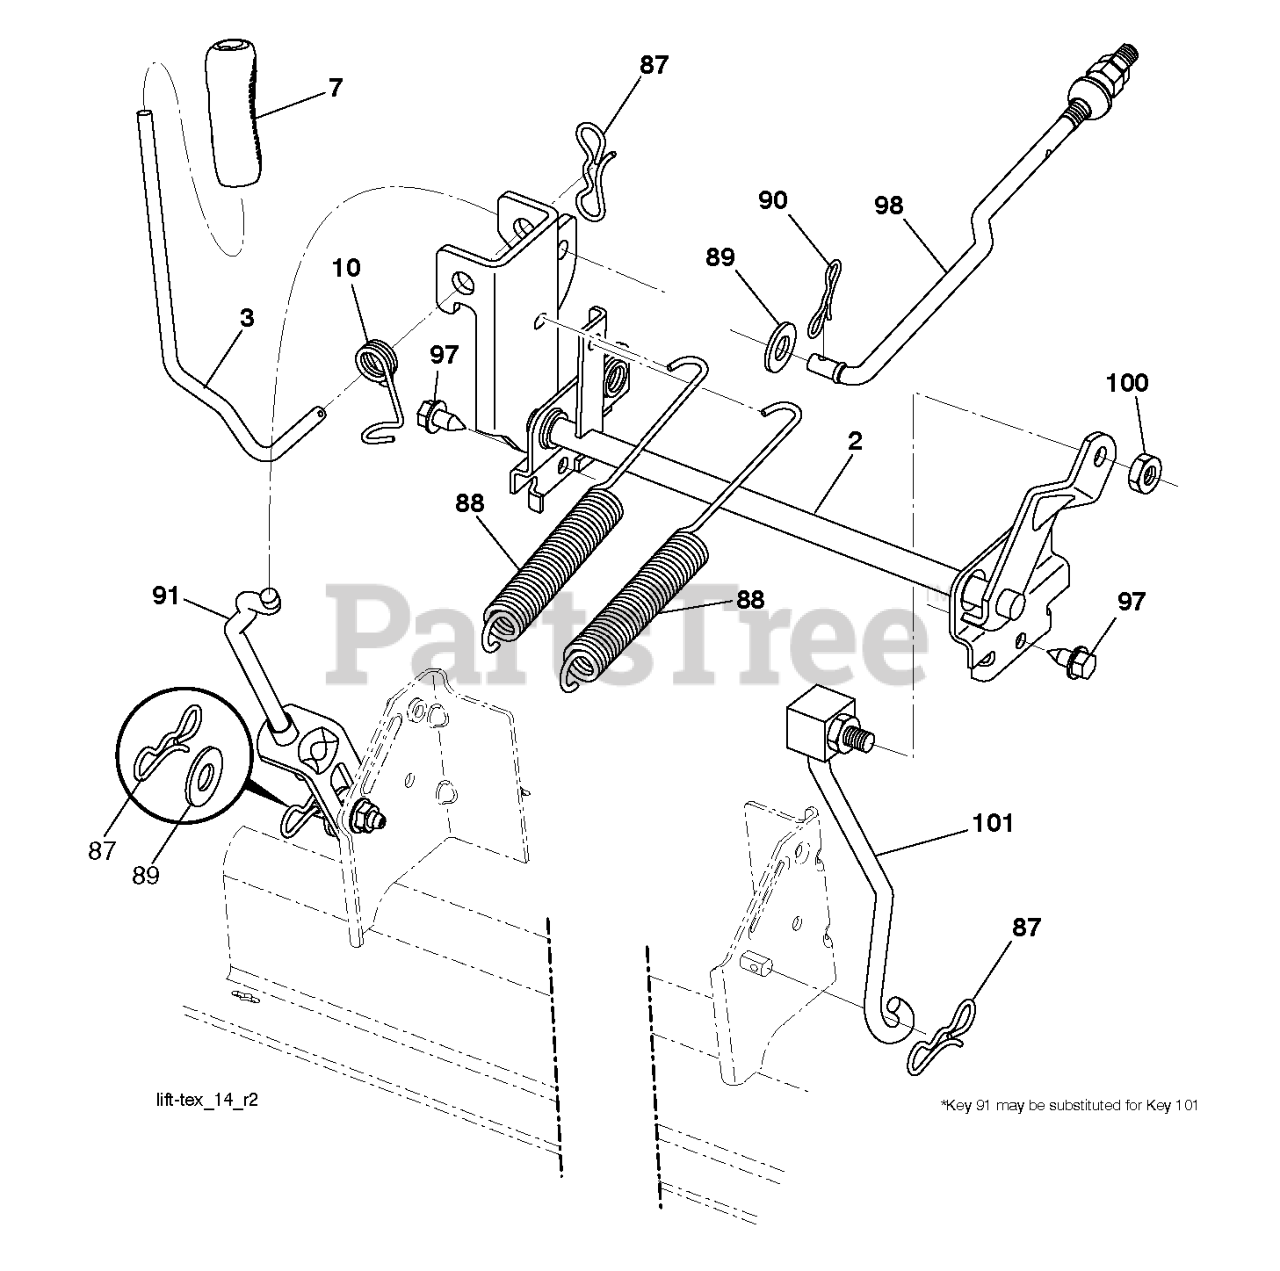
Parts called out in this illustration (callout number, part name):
2	SHAFT.ASM.LIFT.CROSS.H
3	LEVER.LIFT.HANDLE.LT
7	GRIP.HANDLE.LIFT.PVC.BLACK
10	SPRING.TORSION.LIFT.HANDLE
87	PIN.COTTER.7/16.BOW TI.
88	SPRING.LIFT.ASSIST
89	WASHER.CLEAR.ZINC
90	PIN.COTTER.5/16.BOW TI
91	LINK.ASM.LIFT.REAR
97	SCREW, 3/8-16X3/4
98	LINK.ASM.SUSP.FRONT.MWR.10.5
100	LOCKNUT
101	LINK.ASM.LIFT.FIXE.38/42/46"
